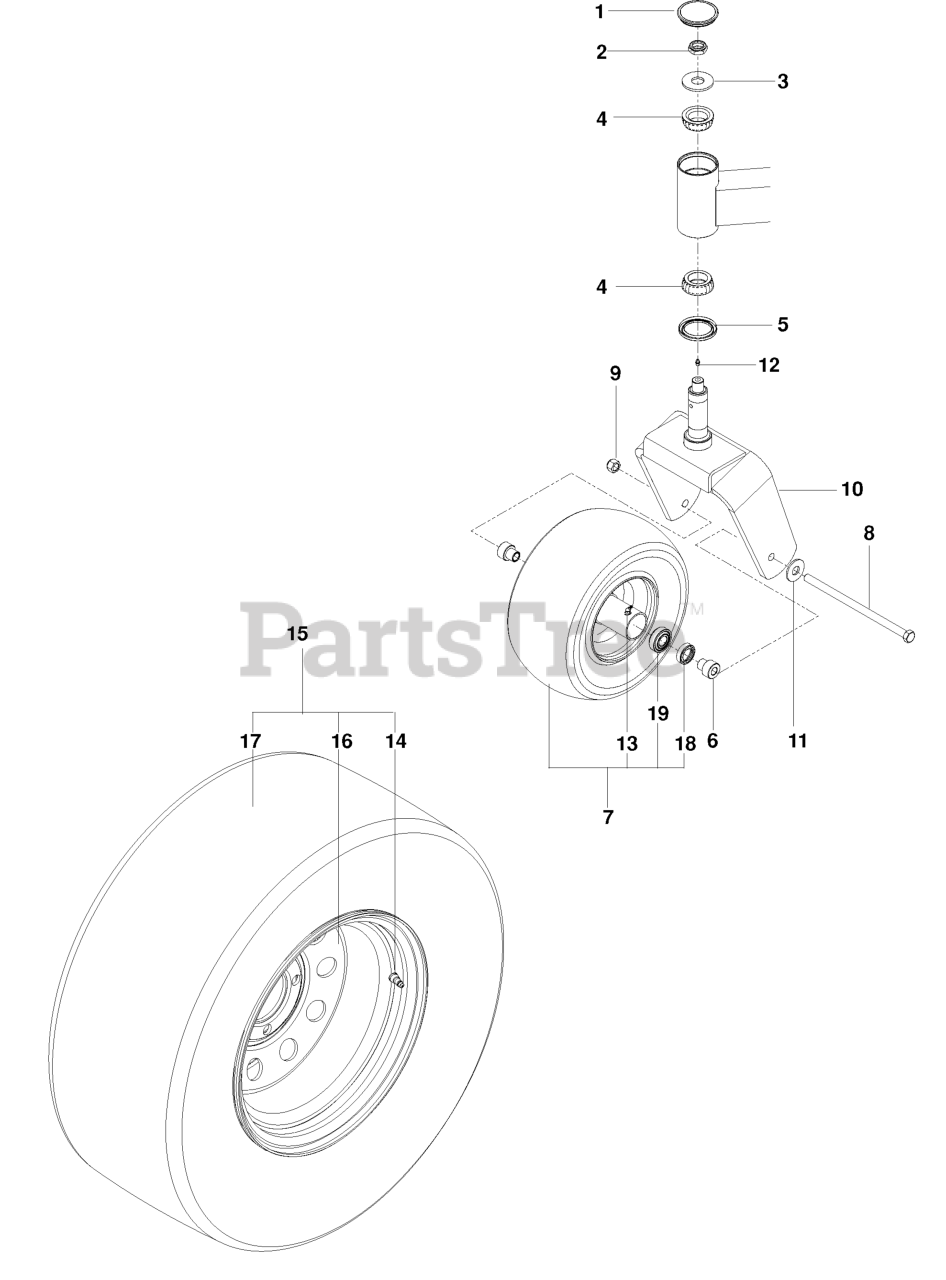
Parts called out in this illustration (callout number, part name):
2	NUT, 3/4-16 HEX THIN NYLOC ZD
3	WASHER, 3/4 HARDENED
4	BEARING W/CUP TAPPER ROLLER
5	SEAL, BEARING
6	AXLE SPACER
7	Tire Assy 13 X 6.5, Flt Free
8	HEX SCREW 1/2-13 X 9.5 GR5
9	NUT, 1/2-13 HEX FLG NYLOC ZD
10	FORK.CASTER.ORANGE
11	WASHER 1/2" FLAT
12	ZERK
13	ZERK
14	VALVE STEM TR-412
15	WHEEL/TIRE.ASM SILV 23X10.5-12
16	RIM, 12 X 8.5, 1.125" NEG OS
17	TIRE.TURF.MASTER.23X10.5-12
19	TAPERED BEARING W/RACE
